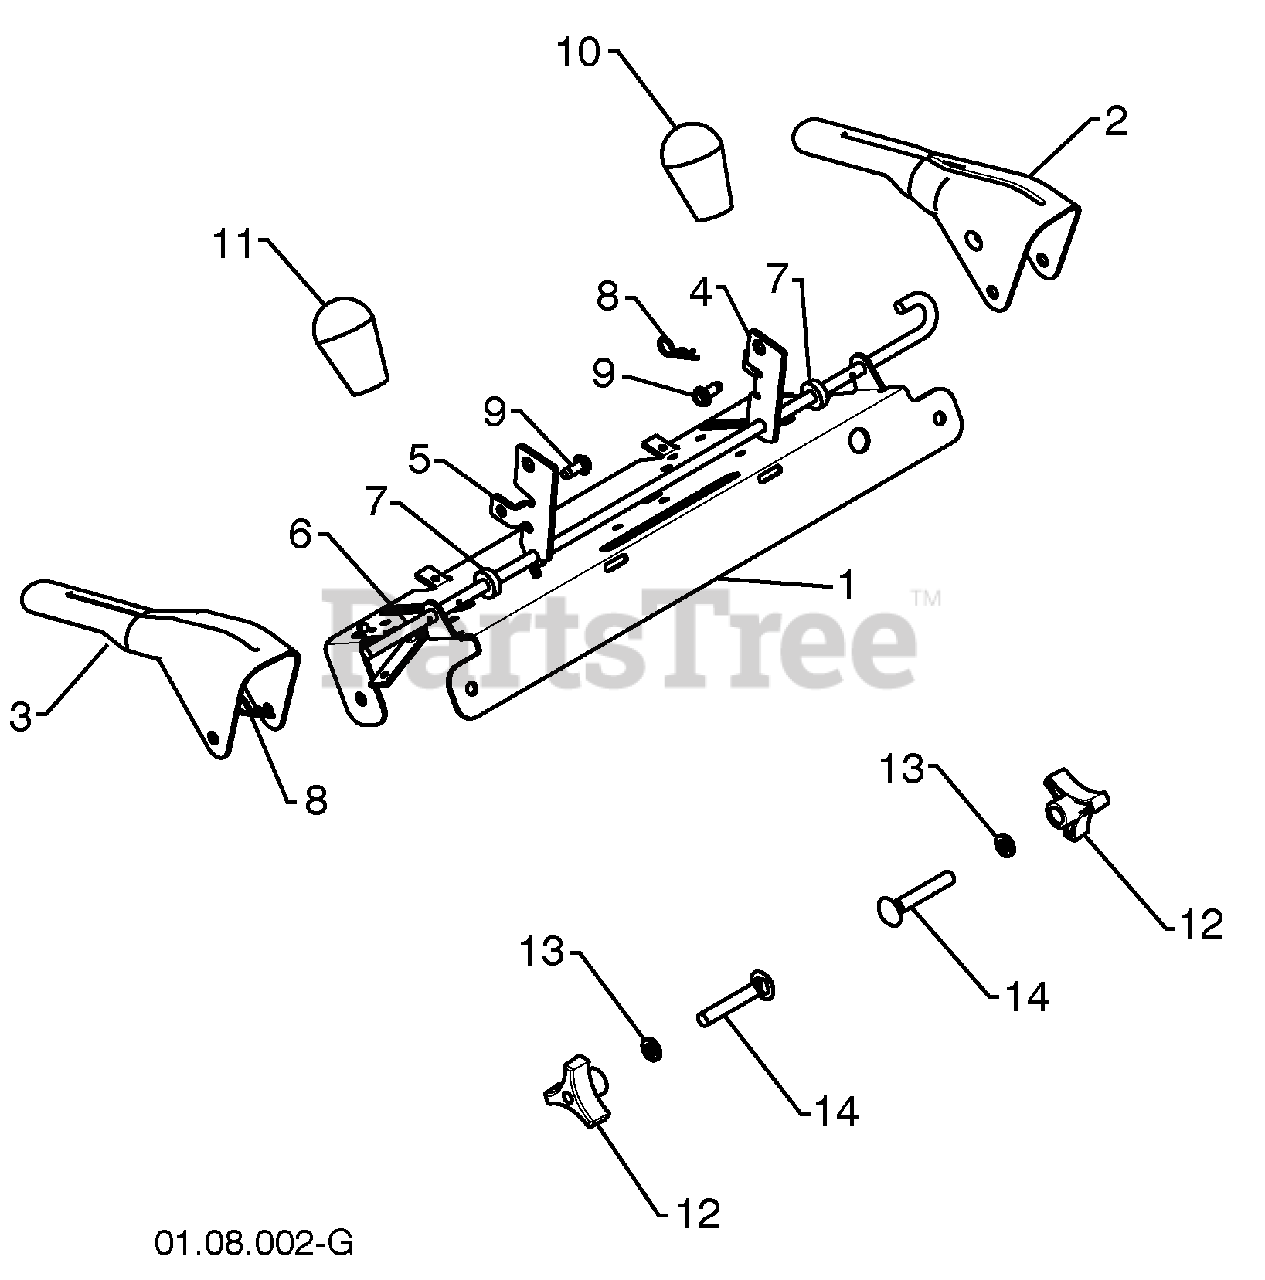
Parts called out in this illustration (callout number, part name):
2	CONTROL LEVER LH
3	CONTROL LEVER RH
4	TRACTION ROD ARM
5	IMPELLER ROD ARM
6	INTERLOCK ROD
8	RETAINER
9	SCREW 1/4-20 X .62
10	KNOB BLACK
11	KNOB RED
12	HANDLE KNOB
13	WASHER 3/8
14	CARRIAGE BOLT 3/8-16 X 2.25
